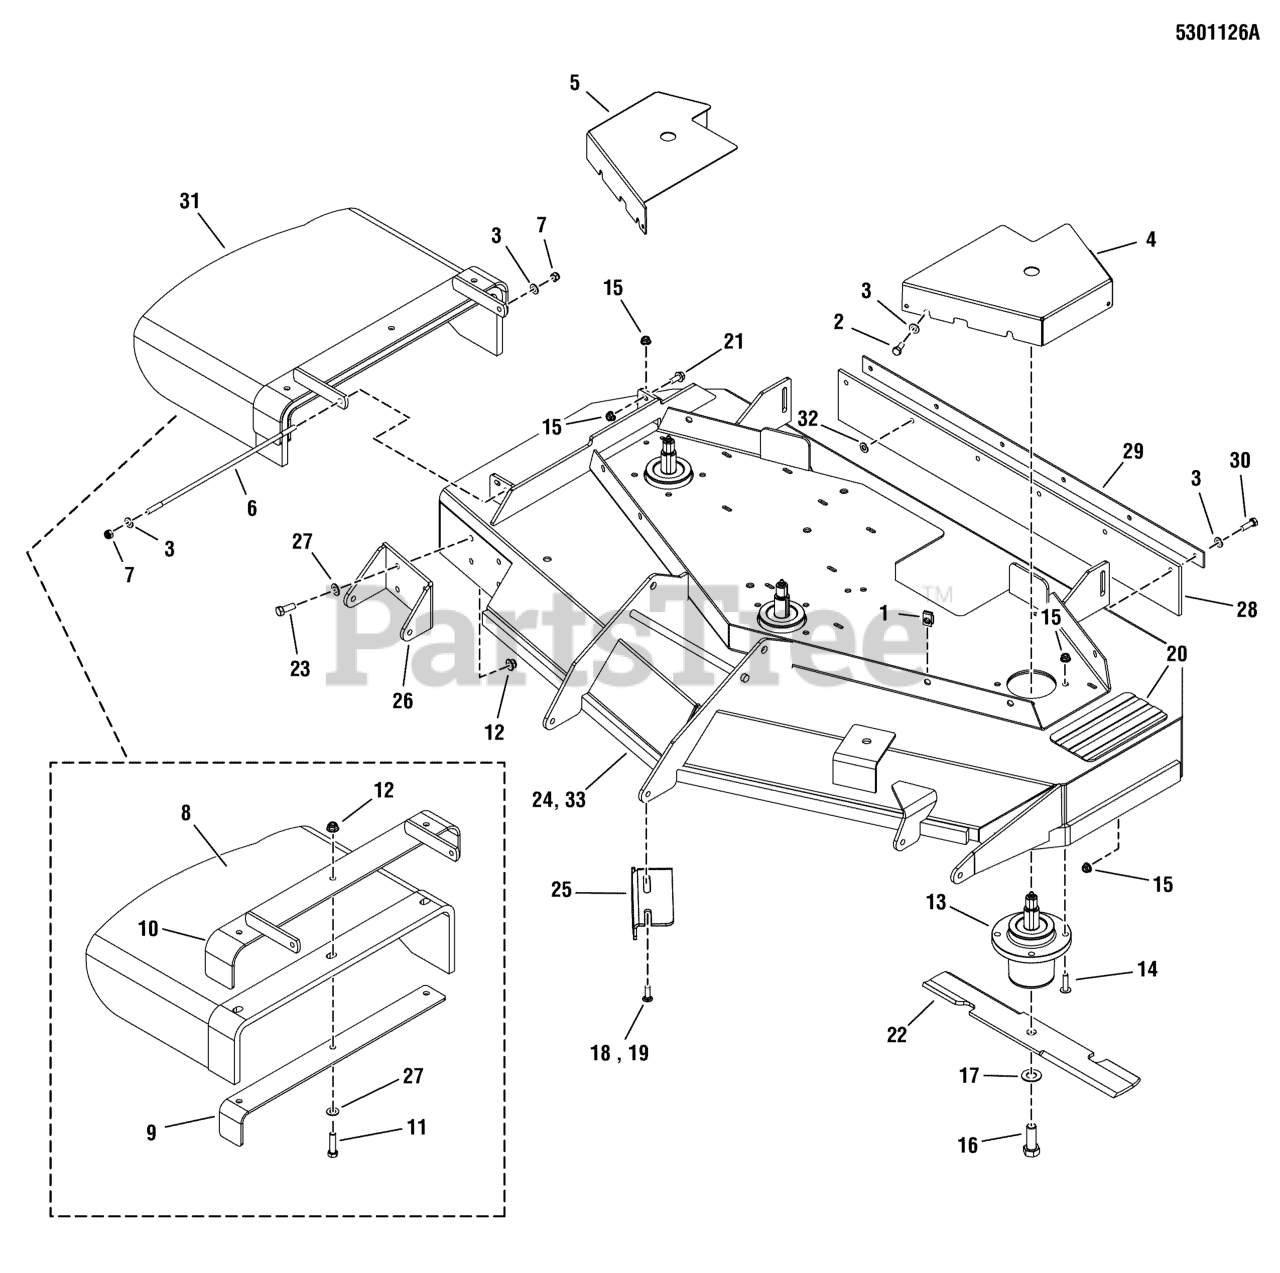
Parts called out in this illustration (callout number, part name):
1	BODY CLIP, 5/16-18-7GA MATERIAL
2	BOLT, 5/16-18 X 3/4 GD5
3	WASHER, 5/16" SAE
4	GUARD, 52" DECK - LH
5	GUARD, 52" DECK - RH
6	ROD, CHUTE MOUNT, 61, CZ
7	NUT, 5/16-24 HEX NYLON LOCK
8	CHUTE, DISCHARGE, RUBBER, 61/72, BENT
9	SUPPORT, DISCHARGE CHUTE - BLK
10	WELD, FRAME, CHUTE, 61 - RED
11	BOLT, 3/8-16 X 1-1/2" GD5 CZ
12	NUT, 3/8-16 HEX NYLOCK FLANGE
13	ASSM, SPINDLE, LOW PROFILE
14	BOLT, 5/16-18 X 1 1/4 FLANGE
15	NUT, 5/16-18 HEX NYLOCK FLANGE
16	BOLT, 5/8-11 X 1-3/4 GD8
17	WASHER, 5/8 GRADE 8, YZ
18	BOLT, 5/16-18 X 1, CARRIAGE
19	BOLT, 5/16-18 X 3/4, CARRIAGE
20	SAFETY WALK, 4.00 X 7.50
21	BOLT, 5/16-18 X 3/4 GD5
22	BLADE, 18 X .25 X 2.5, 1 X 3.5 (SET OF THREE)
23	BOLT, 3/8-16 X 1-1/4" GD5 CZ
24	DECK SHELL W/ DECALS
25	PLATE, DEFLECTOR, 52" - BLK
26	PLATE, BRACKET, ANTI SCALP - RED
27	WASHER, 3/8 SAE
28	FLAP, STRIPER
29	PLATE, SUPPORT - BLK
30	BOLT, 5/16-18 X 1 GD5 YZ
31	PURCHASE INDIVIDUAL REPLACEMENT PARTS
32	5/16 PUSH-ON NUT RETAINER, STL, CZ
33	*DECK SHELL W/DECALS
